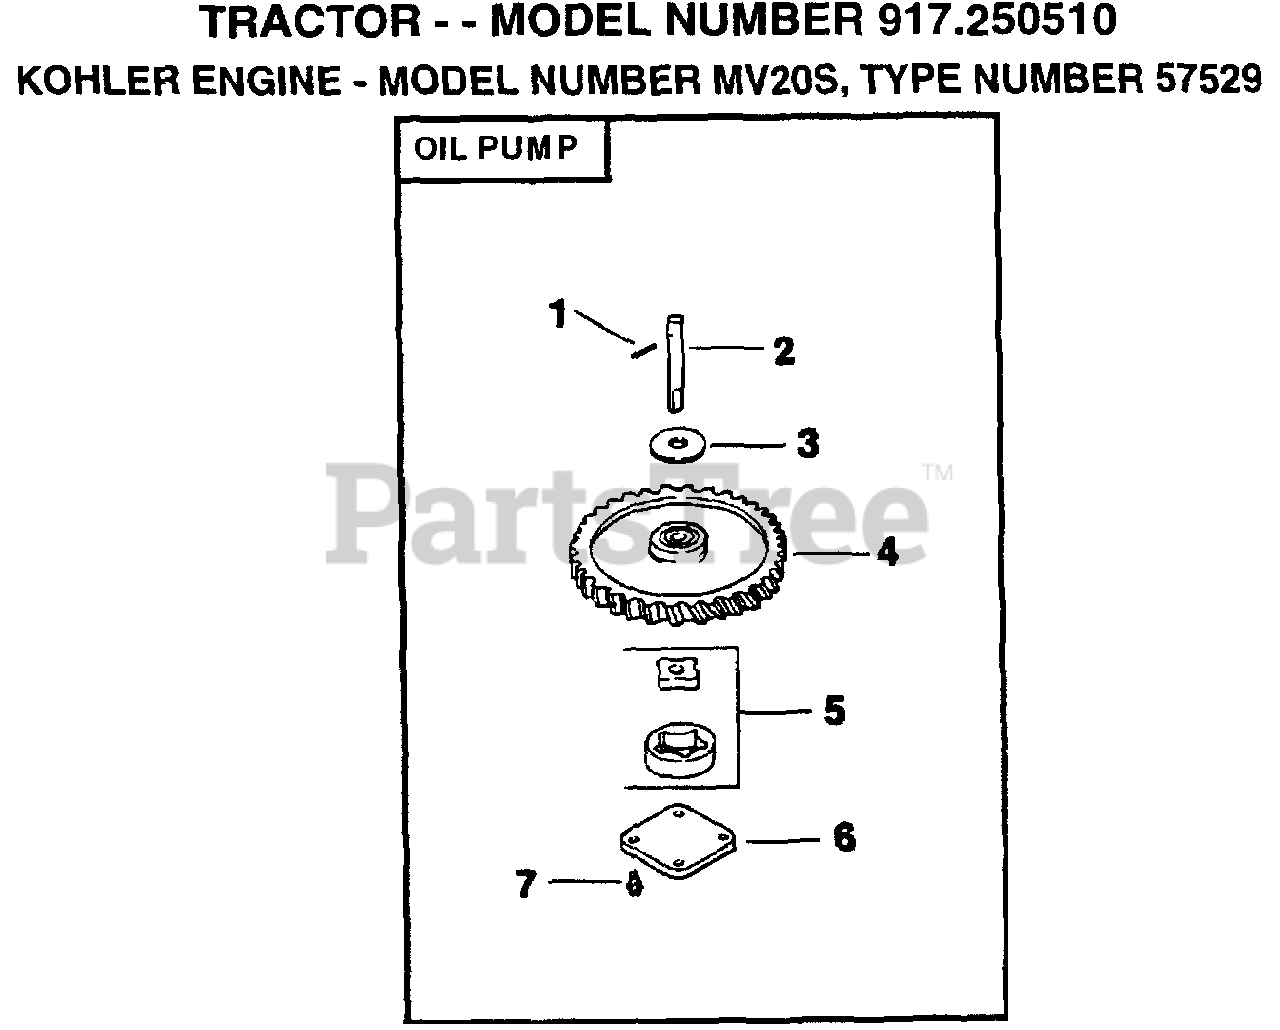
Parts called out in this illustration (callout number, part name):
2	SHAFT, OIL PUMP
4	GEAR OIL PUMP
6	COVER, OIL PUMP
